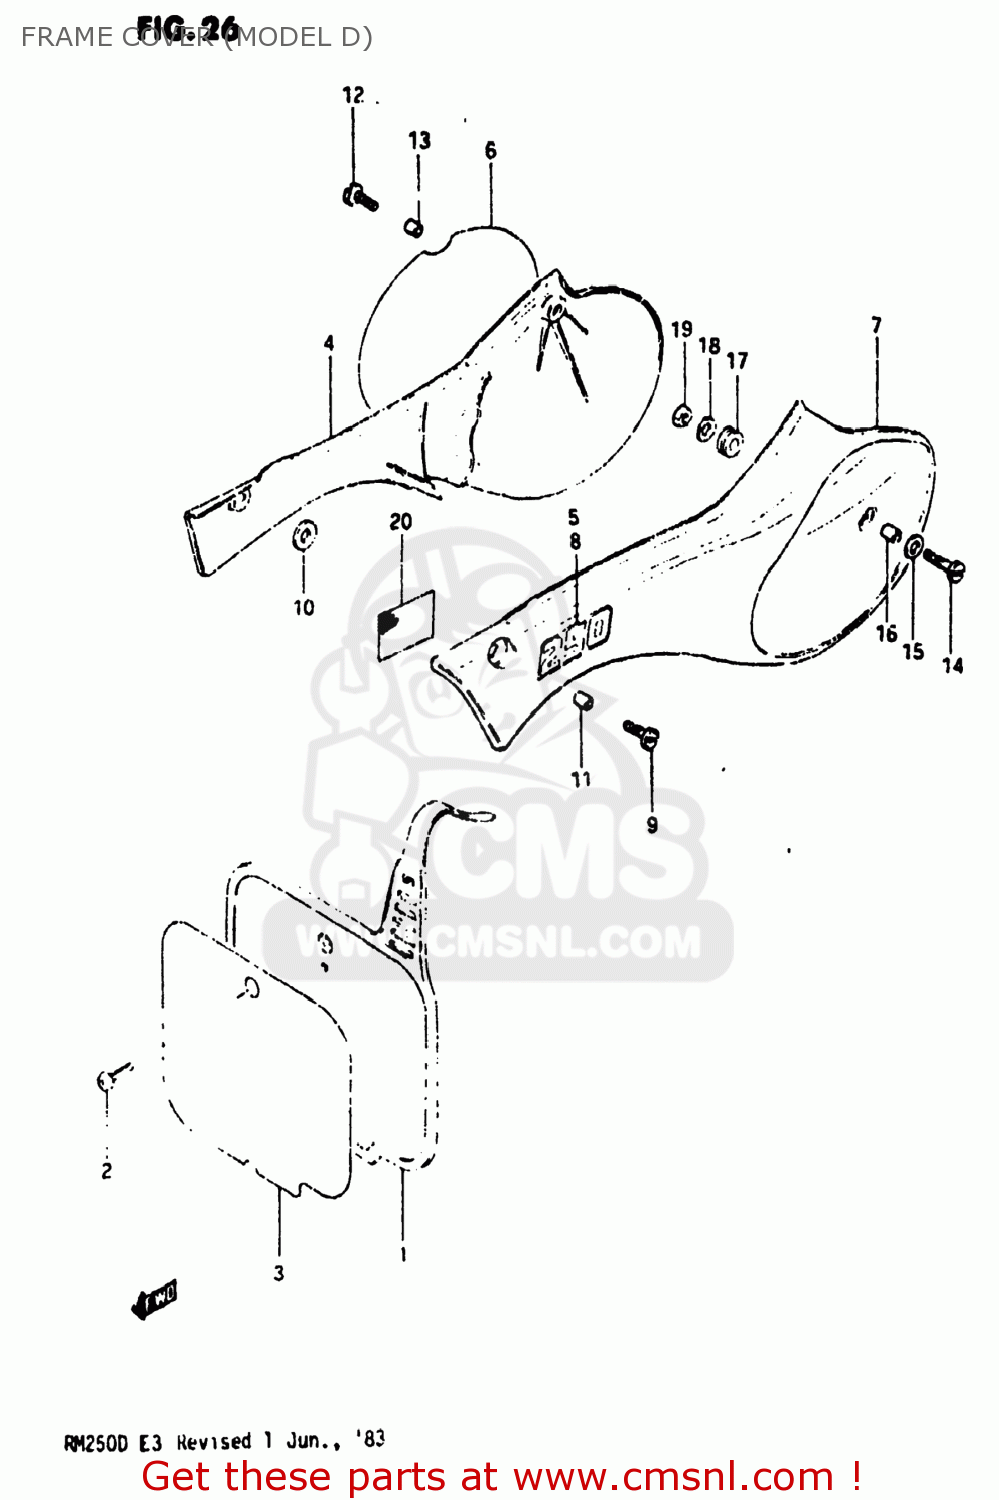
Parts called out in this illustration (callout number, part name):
1	PLATE,NUMBER,FRONT
2	SCREW
3	EMBLEM,FRONT NUMBER PLATE
4	COVER,FRAME,R(YELLOW)
5	EMBLEM,FRAME COVER,RIGHT
6	EMBLEM
7	COVER,FRAME,LEFT
8	EMBLEM,FRAME COVER
9	SCREW(6X14)
10	WASHER, REAR
11	SPACER (6.1X8X3.5)
12	SCREW(6X14)
13	SPACER (6.1X8X3.5)
14	SCREW(6X20)
15	WASHER (6.5X24X1.6)
16	SPACER (6.1X9X9)
17	CUSHION
18	WASHER, REAR
19	NUT 6MM
20	HEAT SHIELD,FRAME COVER
